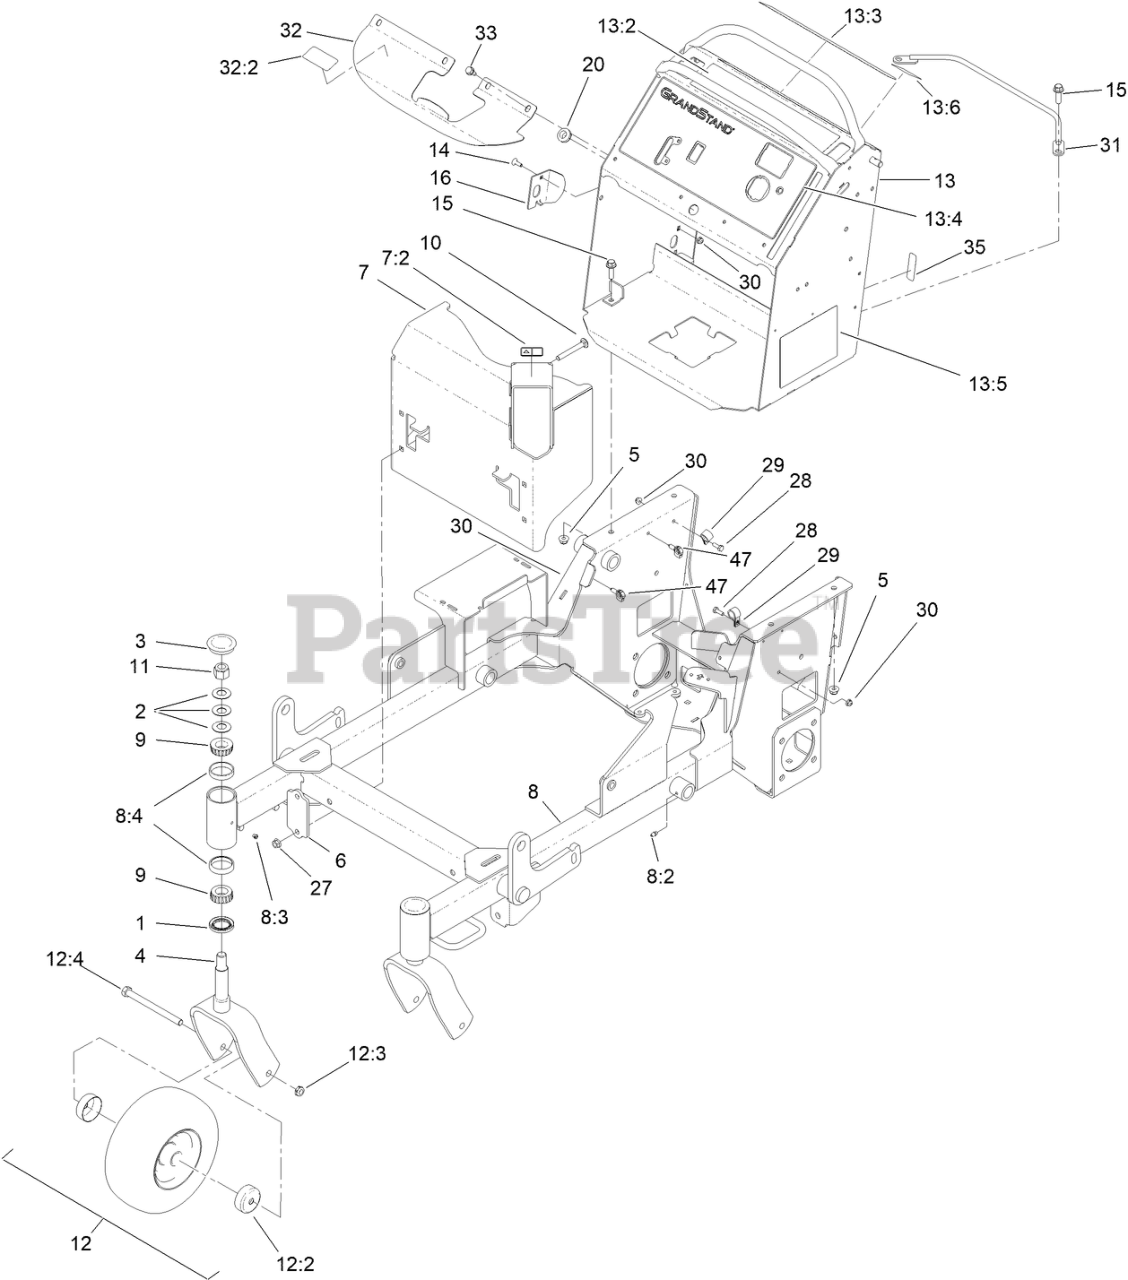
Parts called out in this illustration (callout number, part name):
1	SEAL-GREASE
2	WASHER-BELLVILLE
3	CAP-GREASE
4	FORK-CASTER
5	NUT-HF, NI
6	BRACKET-MOUNTING, GUARD
7	MUFFLER GUARD ASM
7:2	DECAL-WARNING
8	FRAME ASM
8:2	FITTING-GREASE
8:4	CUP-BEARING
9	BEARING-ROLLER, TAPERED
10	SCREW-CARR
11	NUT-LOCK, NI
12	WHEEL, TIRE AND BEARING ASM
12:2	GUARD-SEAL
12:3	NUT-HEX
12:4	SCREW-HH
13	CONTROL TOWER ASM
13:2	DECAL-OPC
13:3	DECAL-WARNING
13:4	DECAL-PANEL, CONTROL
13:5	DECAL-SERVICE AID
13:6	DECAL-STABILITY, CE
14	BOLT-CARR
15	SCREW-HHF
16	PLATE-STRIKER
20	GROMMET
27	NUT-HF
28	SCREW-HH
29	CLAMP-CABLE
30	NUT-HF
31	RETAINER-CABLE
32	COVER-TANK
32:2	DECAL-FILL, FUEL
33	SCREW-HWHTF
35	DECAL-FUSE
47	CLIP-HARNESS
